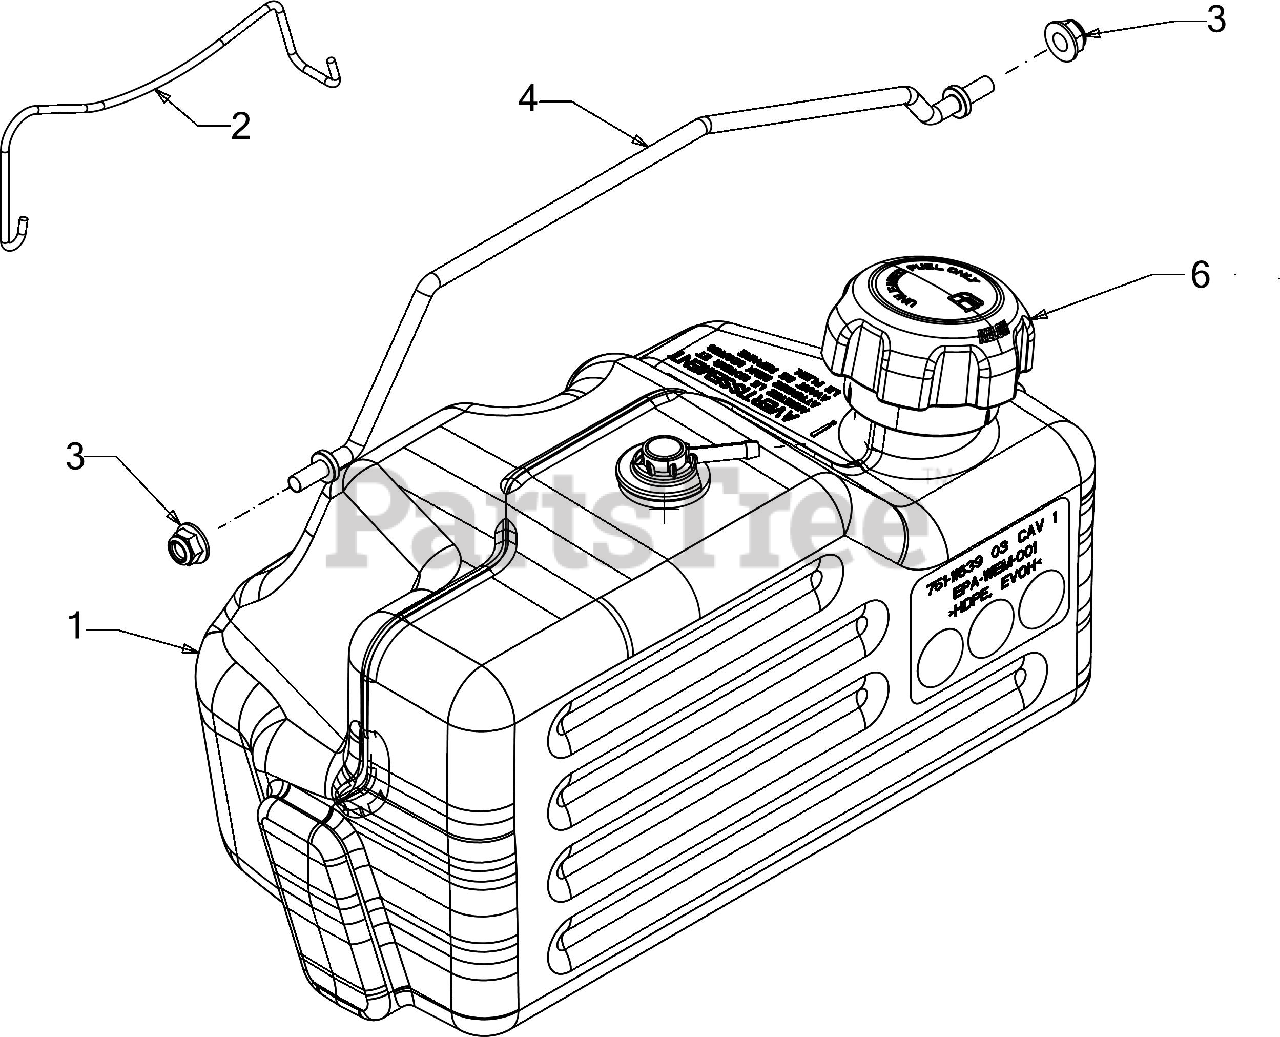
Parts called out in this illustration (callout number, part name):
1	FUEL TANK ASSEMBLY
2	BATTERY ROD ASSEMBLY
4	FUEL TANK CLAMP ROD
5	VENT HOSE 3/16 ID
6	FUEL CAP W/TETHER
